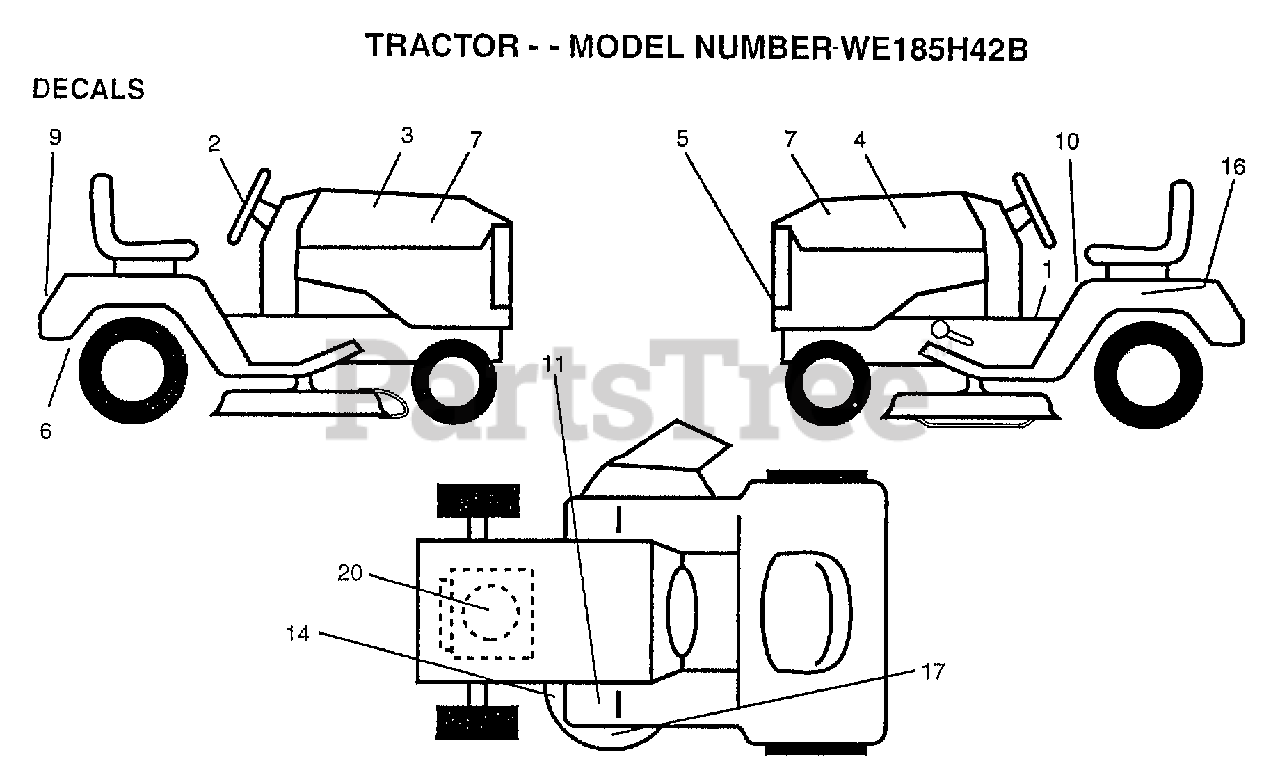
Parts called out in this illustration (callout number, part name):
1	"DECAL INST,SADDLE"
2	"DECAL INS,STRG WH"
3	"DECAL HOOD,RH"
4	DECAL HOOD LH
5	"DECAL GRILLE,LENS"
6	DECAL DRAWBAR LH
7	DECAL PANEL SIDE
9	DECAL-FENDER
10	"DECAL DANGER,FEND"
14	DECAL
16	DECAL.BATRY.3-3908
20	DECAL, HP, ENGINE
